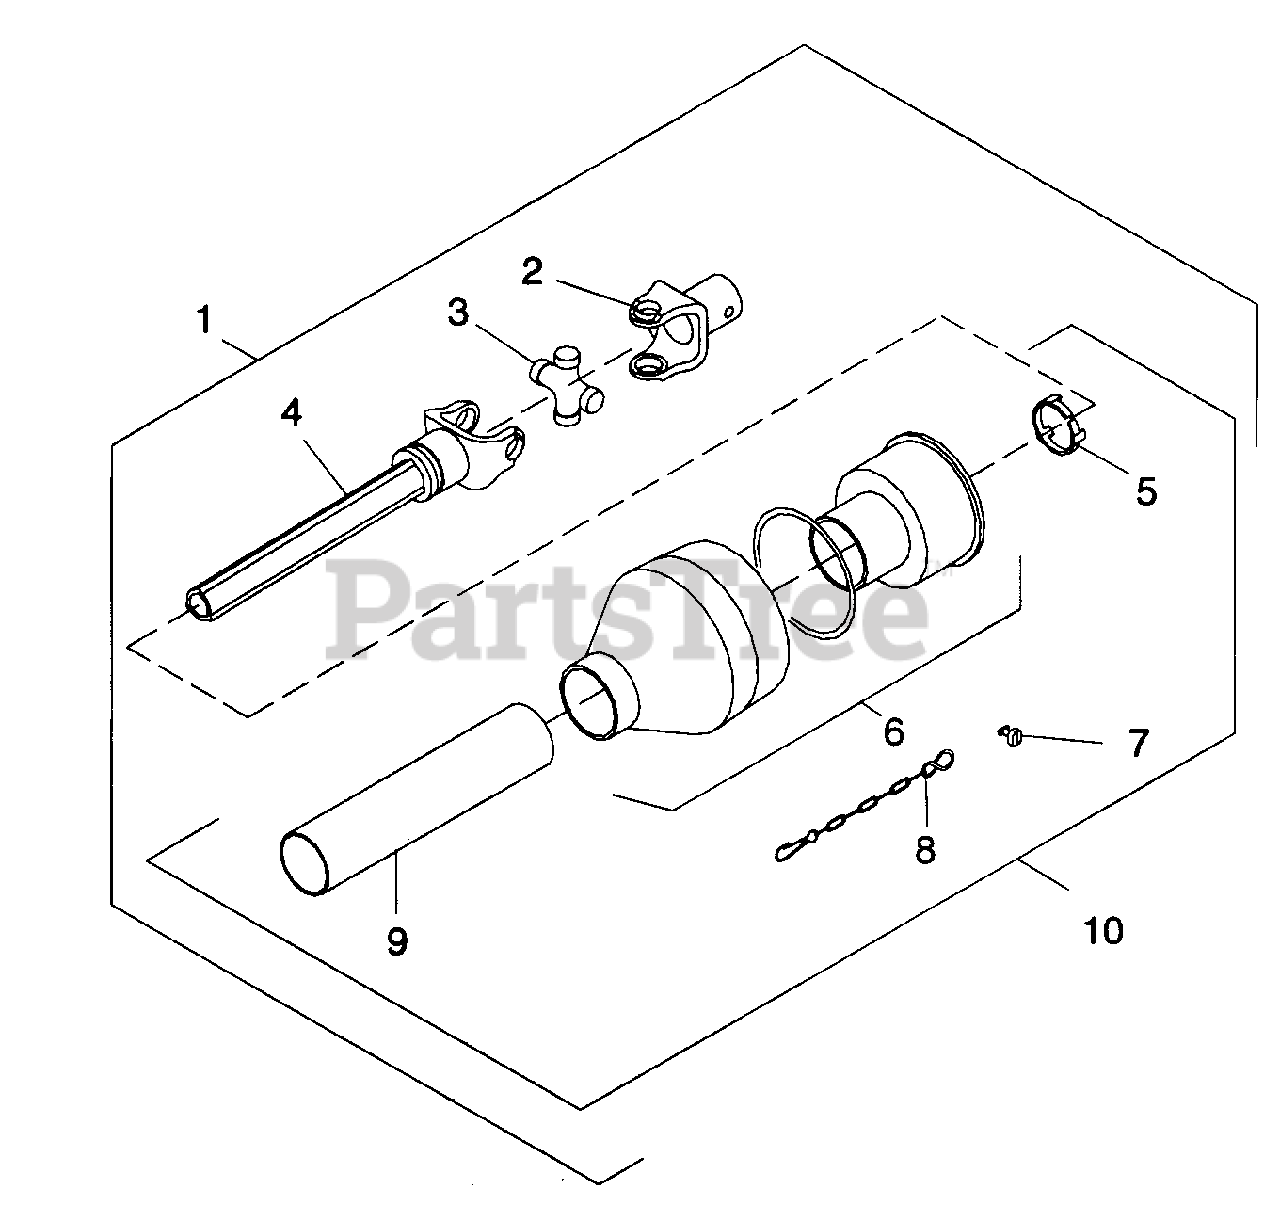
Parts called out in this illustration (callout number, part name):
1	Drive - profile shield 40, 26.2, 1.38 QD
2	40 QD Yoke
3	U-Joint repair kit 40S
4	Yoke and Tube (Profile) 40 x 26.2
5	Drive shield bearing 40
8	Shield tether chain
10	Inner shield assembly complete
